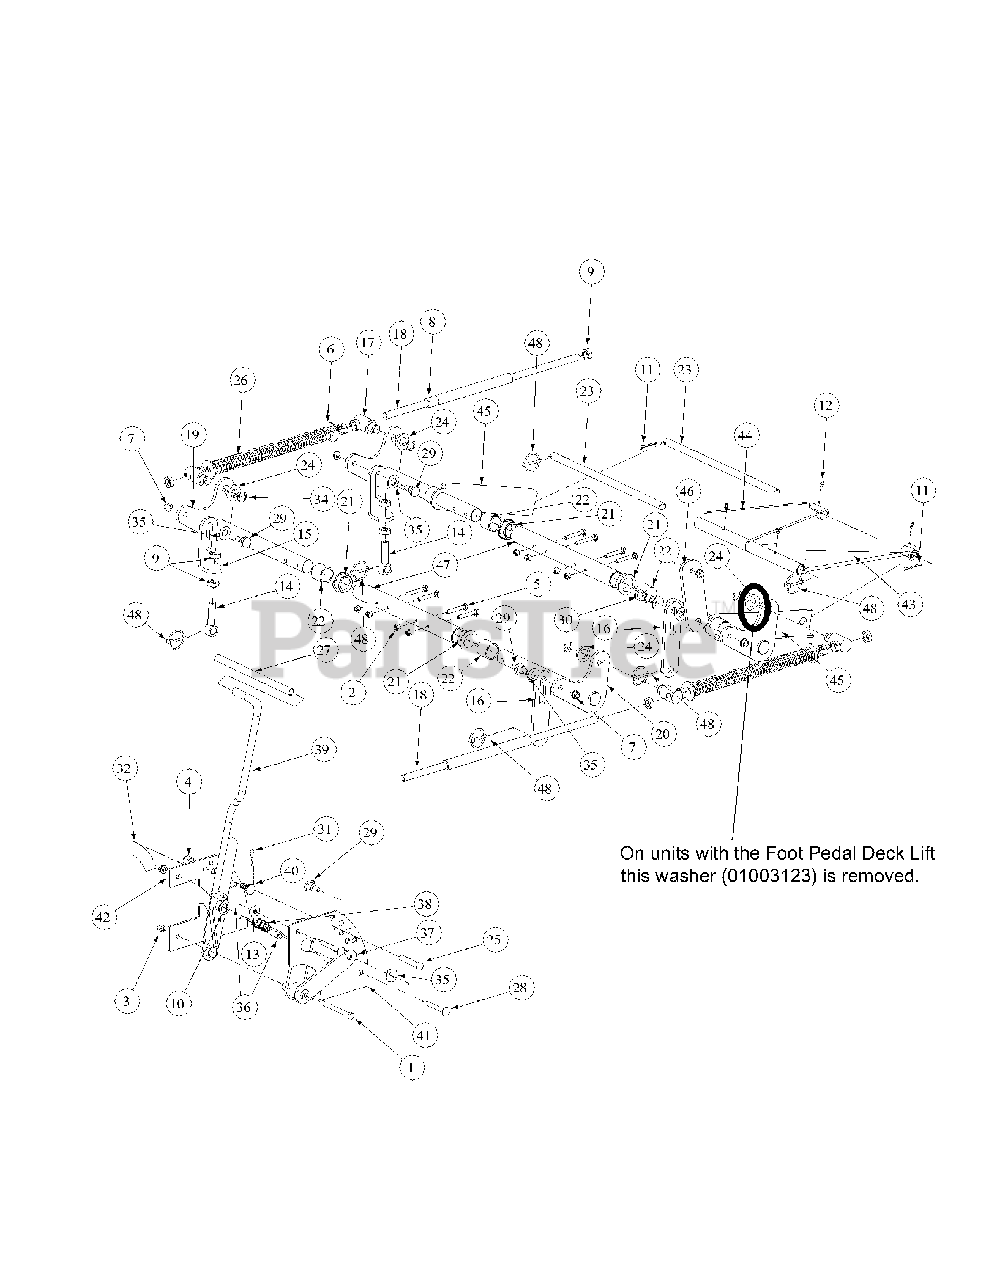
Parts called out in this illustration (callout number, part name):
1	Hex Cap Screw, 3/8-16, 3.75
2	Nut, 5/16-18, Nylock
3	Nylock Insert Lock Nut, 3/8-16
4	Nylock Insert Lock Nut, 1/2-13
5	Hex Cap Screw, 5/16-18 x 2
6	Flat Washer, 5/8
7	Hex Nut, Flange Lock, 3/8-16
8	PVC Hose,5/8 ID x 13/16 OD x 8"
9	Jam Nut, 5/8-11
10	Flat Washer, .06, .776, 1.25
11	Cotter Pin, 3/16 x 1-1
12	Grease Fitting, 1/4-28 x 3/16
13	Idler Washer
14	Eye Bolt,5/8ID
15	Eye Bolt Mount Link, 5/8 ID
16	Deck Link
17	Ferule Lift
18	Lift Connector Rod
19	Bellecrank Weldment Lift, Left Hand
20	Bellecrank Weldment Lift, Right Hand
21	Hex Flange Bearing, 1.25 ID
22	Frame Lift Spacer
23	Front Lift Link, Rod Mount
24	Spacer, .812 ID x .268 Lg.
25	Clevis Pin, .500 Dia. x 2.625 Lg.
26	Lift Compression Spring
27	Lift Handle Grip
28	Carriage Bolt, 3/8-16, 2.75
29	Shoulder Screw, 0.625 OD x .437 Lg.
30	Shoulder Screw, 0.625 OD x .830 Lg.
31	Cotter Pin, .148 x 3.00
32	Decal Height Indicator
34	E Clip, 3/4 Dia.
35	Nylon Flat Washer, 5/8
36	Spacer, .39 ID x .63 OD x 1.442
37	Lift Pivot Assembly
38	Lift Handle Spring
39	Lift Handle Assembly
40	Shoulder Screw, 5/8 OD x 0.264
41	Outer Lift Index Plate
42	Inner Lift Index Plate
43	Bearing Lift Brace Assembly, Right Hand
44	Bearing Lift Brace Assembly, Left Hand
45	Front Frame Strut Assembly
46	Lift Link Adjustment
47	Lift Shaft Holder
48	Linch Pin, 3/16
